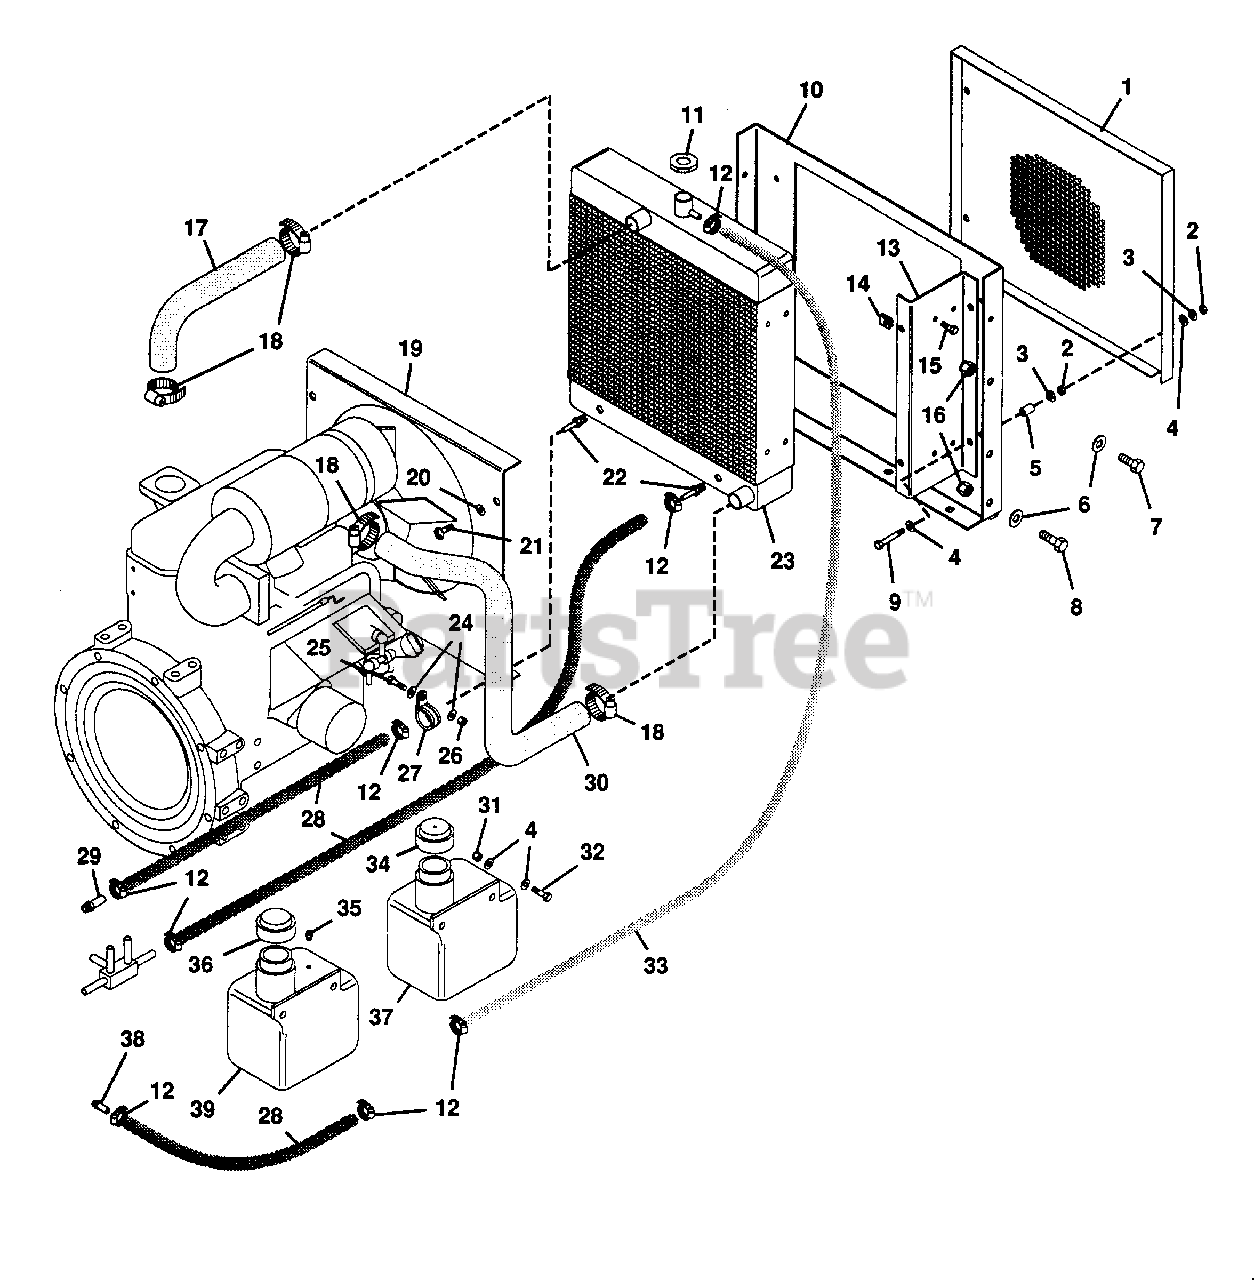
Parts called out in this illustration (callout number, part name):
1	Cover, Air
2	Nut, Hex 5/16-18
3	Washer, Lock 5/16 Reg.
4	Washer, Flat .344x.688x.065
5	Stop, Chute
6	Washer, Flat .531x1.062x.095
7	Bolt, Hex 1/2-13x1.00
8	Bolt, Hex 1/2-13x1.50
9	Bolt, Hex 5/16-18x2.00
10	Mount, Radiator
11	Cap, Radiator
12	Clamp, Hose
13	Bracket, Radiator
14	Nut, Retainer
15	Bolt, Hex 5/16-18x.50
16	Nut, Lock 1/2-13
17	Hose, Upper Radiator
18	Clamp, Hose
19	Cover, Fan
20	Washer, Flat .281x.625x.065
21	Screw, Machine 1/4-20 PHD
22	Adapter, #4404-6-6
23	Radiator, Flat Plate
24	Washer, Flat .406x.812x.065
25	Bolt, Hex 3/8-16x1.00
26	Nut, Lock 3/8-16
27	Clamp, Steel .625
28	Hose, Hydraulic
29	Adapter, #4604-6-6
30	Hose, Lower Radiator
31	Nut, Lock 5/16-18
32	Bolt, Hex 5/16-18x1.00
33	Hose, 5/16 ID
34	Cap, 1-5/8 Vented(Black)
35	Plug, 1/8 Vent
36	Cap, 1-5/8 Non-Vented(White)
37	Tank, Plastic 1.5 Qt.
38	Connector, Hose
39	Tank, Plastic 1.5 Qt.
